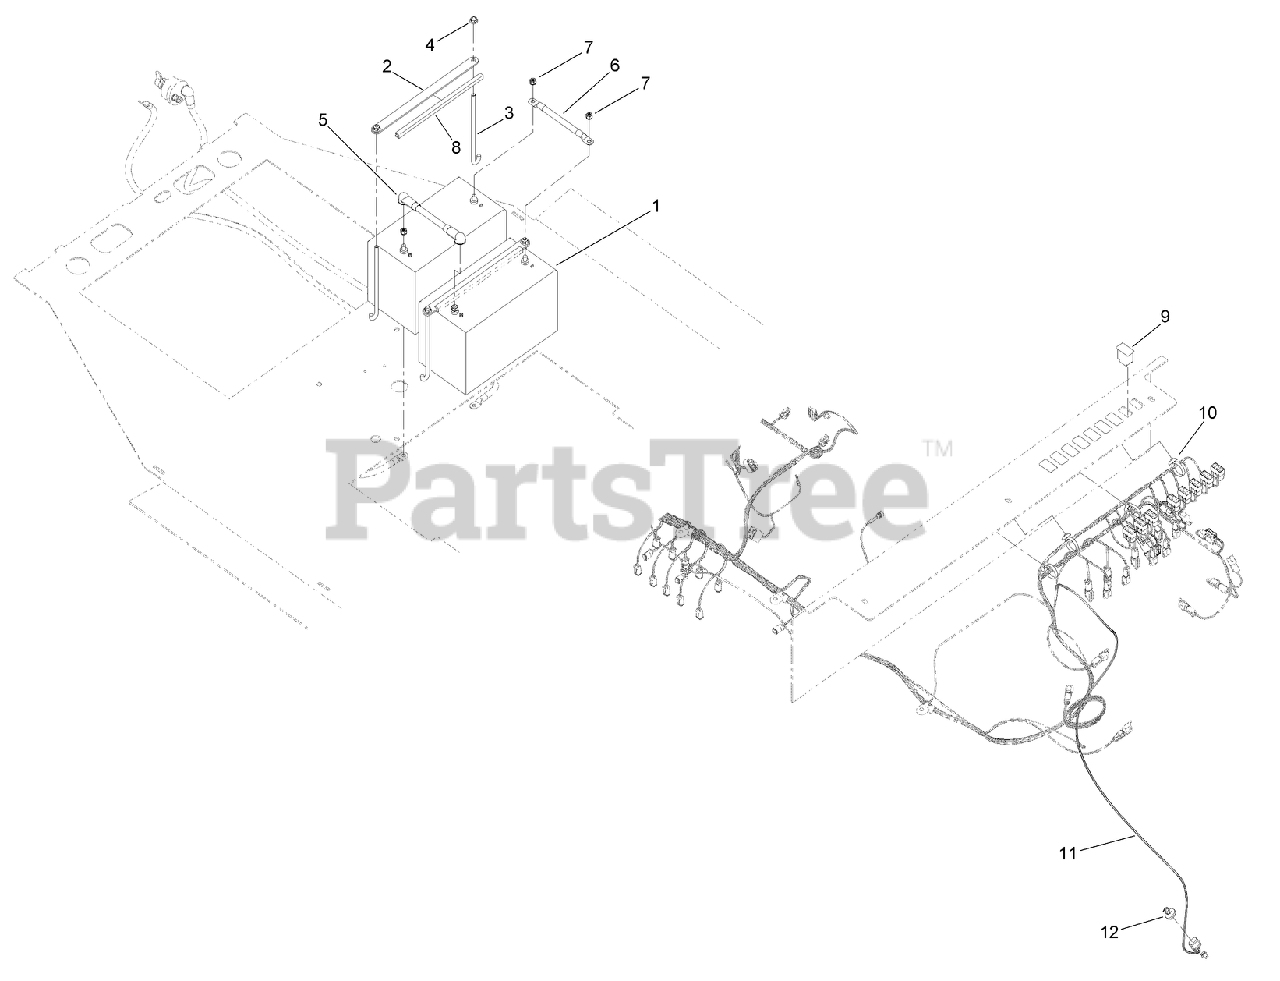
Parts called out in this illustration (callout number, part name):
1	BATTERY
2	PLATE-HOLD DOWN, BATTERY
3	BOLT-HOLDDOWN, BATTERY
4	NUT-HF, NI
5	CABLE-BATTERY, POSITIVE
6	CABLE-BATTERY, NEGATIVE
7	NUT-KEPS
8	TRIM-BATTERY
9	PLUG-PANEL
10	TIE-BUTTON HEAD
11	HARNESS WIRE, BOOM HOME
12	HARNESS-WIRE, PROX SENSOR JUMPER
